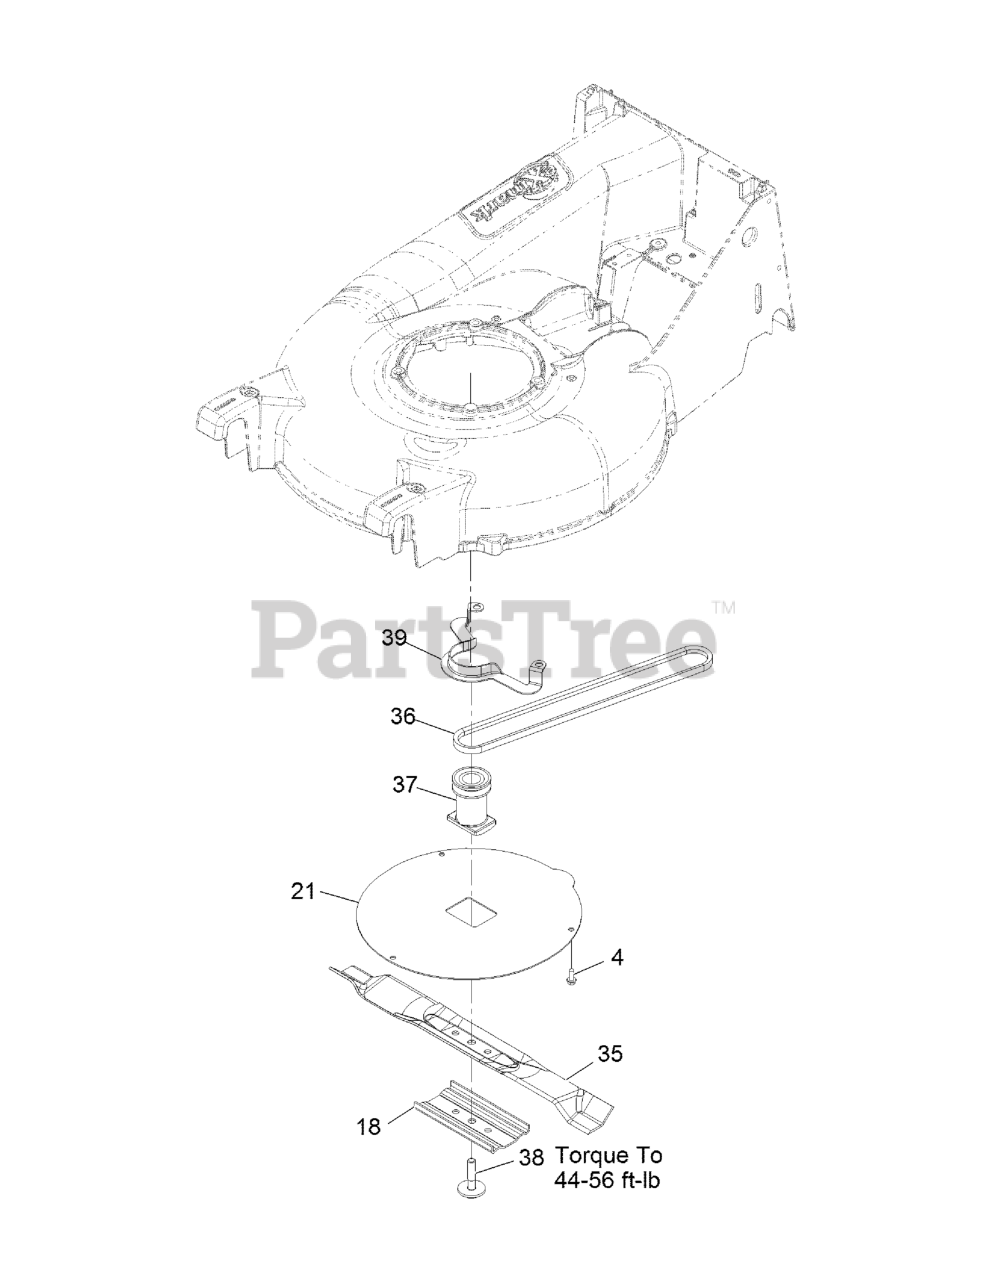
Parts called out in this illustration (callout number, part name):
4	SCREW-HWH
18	SUPPORT-BLADE
35	Blade - Medium Lift, 20.5
36	BELT,3L P21 DRIVE
37	BLADE-ADAPTER
38	BOLT-BLADE, SEM
39	GUIDE-BELT
